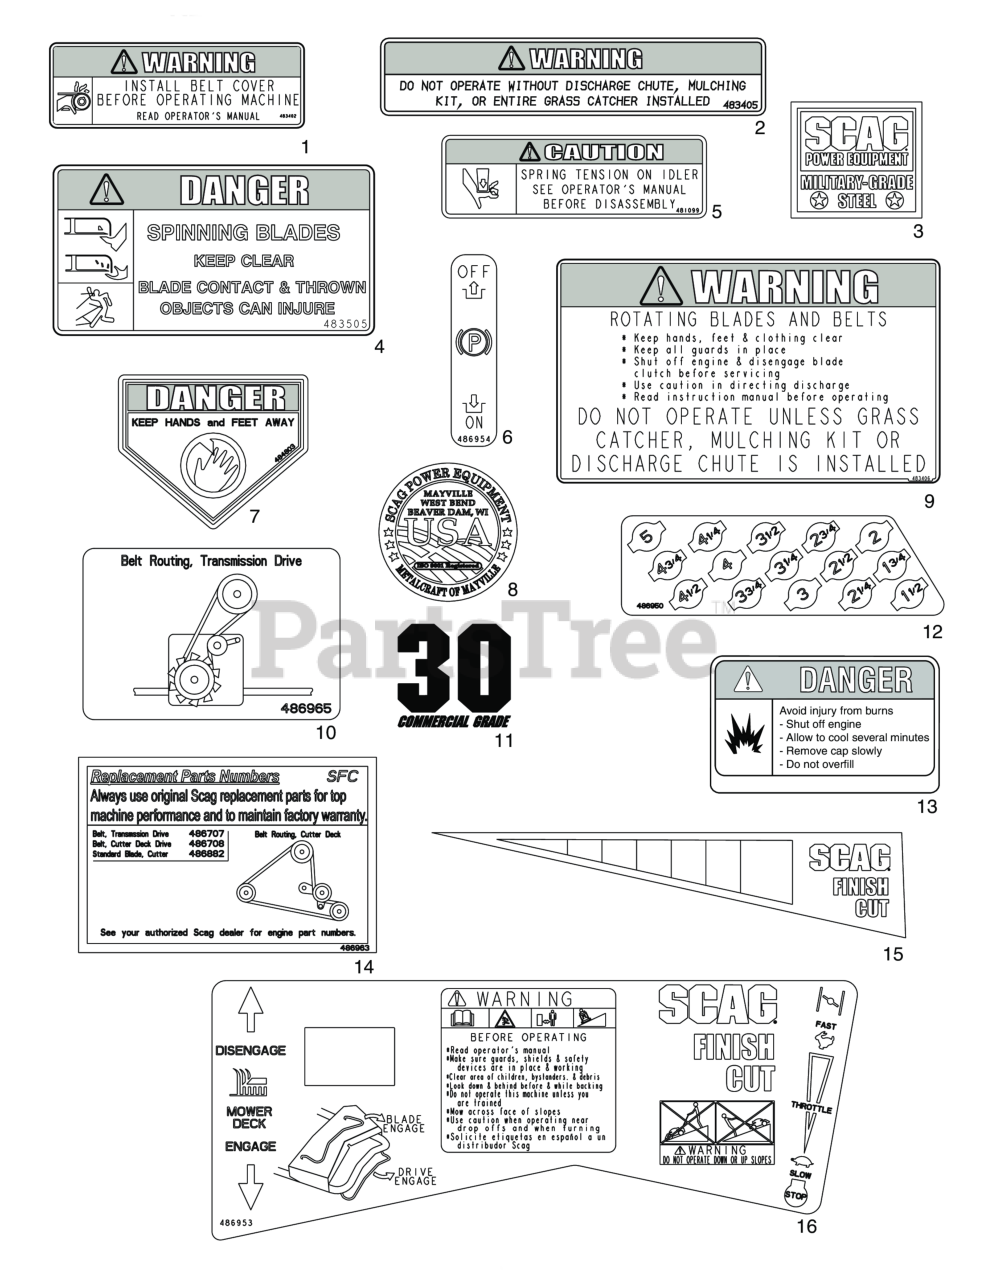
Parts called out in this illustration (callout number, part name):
1	Decal, Warning - Belt Cover
2	Decal, Warning-Discharge
3	Decal, Military Grade
4	Decal, Spinning Blades
5	DECAL, SPRING LOADED IDLER
6	Decal, Parking Brake
7	Decal, Danger - Cut Finger
8	Decal, Metalcraft - USA
9	Decal, Warning - Rotating Blades
10	Decal, Belt Routing
11	Decal, 30 Commercial Grade
12	Decal, Cut Height
13	Decal, Fuel Tank
14	Decal, Replacement Parts
15	Decal, Belt Cover
16	Decal, Instrument Panel
